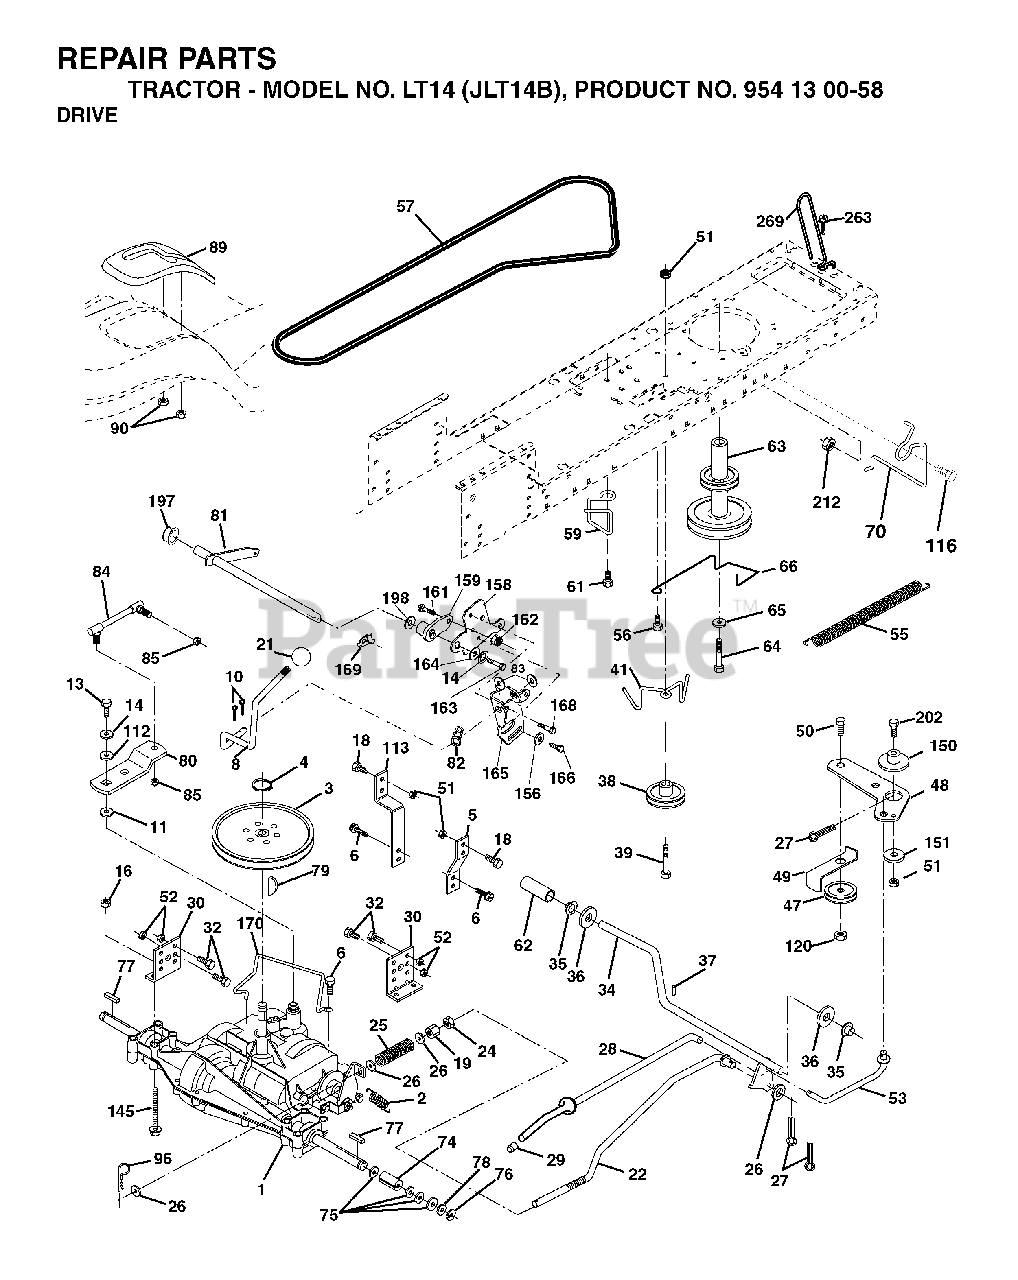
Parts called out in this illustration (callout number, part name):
2	SPRING,BRAKE RETURN
3	PULLEY TRANS
4	RETAINING RING LT
5	STRAP TORQUE
6	SCREW 5/16"
8	ROD SHIFT FENDER ADJUST STLT
10	PIN COTTER
11	WASH-SHFT PLT LT
13	BOLT 1/4-28X3/4
14	LOCKWASHER
16	NUT.71038.31-18.HEX.NYLOCK
19	NUT
21	KNOB.DUCKHEAD.1/2
22	ROD BRAKE
24	NUT
25	SPRING ROD LT
27	COTTER PIN
28	ROD, PARKING BRAKE
29	PLUNGER CAP
30	BRKT, MOUNT TRNSAXLE
32	BOLT
34	SHAFT, FOOT PEDAL
35	BEARING.NYLON
36	WASHER LT
37	DRIVE PIN
38	PULLEY IDLER COMPOSITE
39	BOLT
41	KEEPER, BELT IDLER
47	IDLER PULLEY
48	BELLCRANK, CLUTCH
49	RETAIN BELT
50	BOLT.3/8-16X1.50
51	LOCKNUT
52	LOCKNUT
53	LINK, CLUTCH LT
55	SPRING, RETURN LT
56	SCREW 3/8-16X.875
57	V-BELT
59	KEEPER, BELT CENTER
61	SCREW 3/8-16X.875
62	PEDAL COVER T
64	BOLT
65	LOCKWASHER
66	KEEPER BELT ENGINE
74	SPACER AXLE
76	E-RING LT
77	SQUARE KEY
80	ARM SHIFT
82	SHIFT SPRING
83	WASHER
85	NUT LOCK CENTER 1/4 -28 FNTHD
89	CONSOLE.SHIFT.STLT.6SP.BLACK
96	RETAINER M
112	WASHER LT
113	STRAP TORQUE LH LT
116	BOLT D
120	NUT LOCK FLG 3/8-16 UNC
150	SPACER, RETAINER
151	WASHER 12/32X2X10GA
156	WASHER.SRRTD.5/16
158	BRACKET
159	HUB
161	BOLT
162	NUT.CROWNLOCK.1/4
165	RP BRACKET
168	BOLT.SHOULDER.5/16-18X
169	PLATE.FASTENING.CROSS.SHAFT
170	KEEPER BELT T/A
197	NYLINER SNAP 5/8" ID
198	WASHER.NYL.7/8IDX.105"HYD CR
202	BOLT
212	NUT
263	SCREW, 3/8-16X3/4
